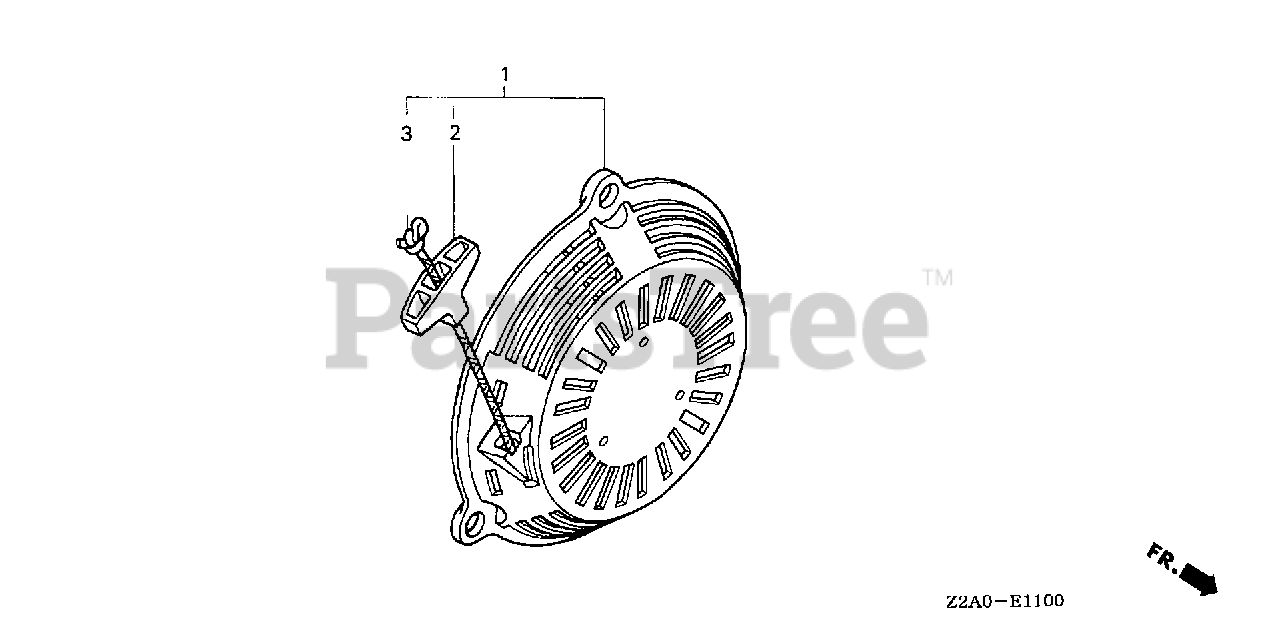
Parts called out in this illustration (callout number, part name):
1	STARTER ASSY., RECOIL *NH1* (SHORT ROPE) (BLACK)
2	GRIP, STARTER
3	ROPE, RECOIL STARTER
